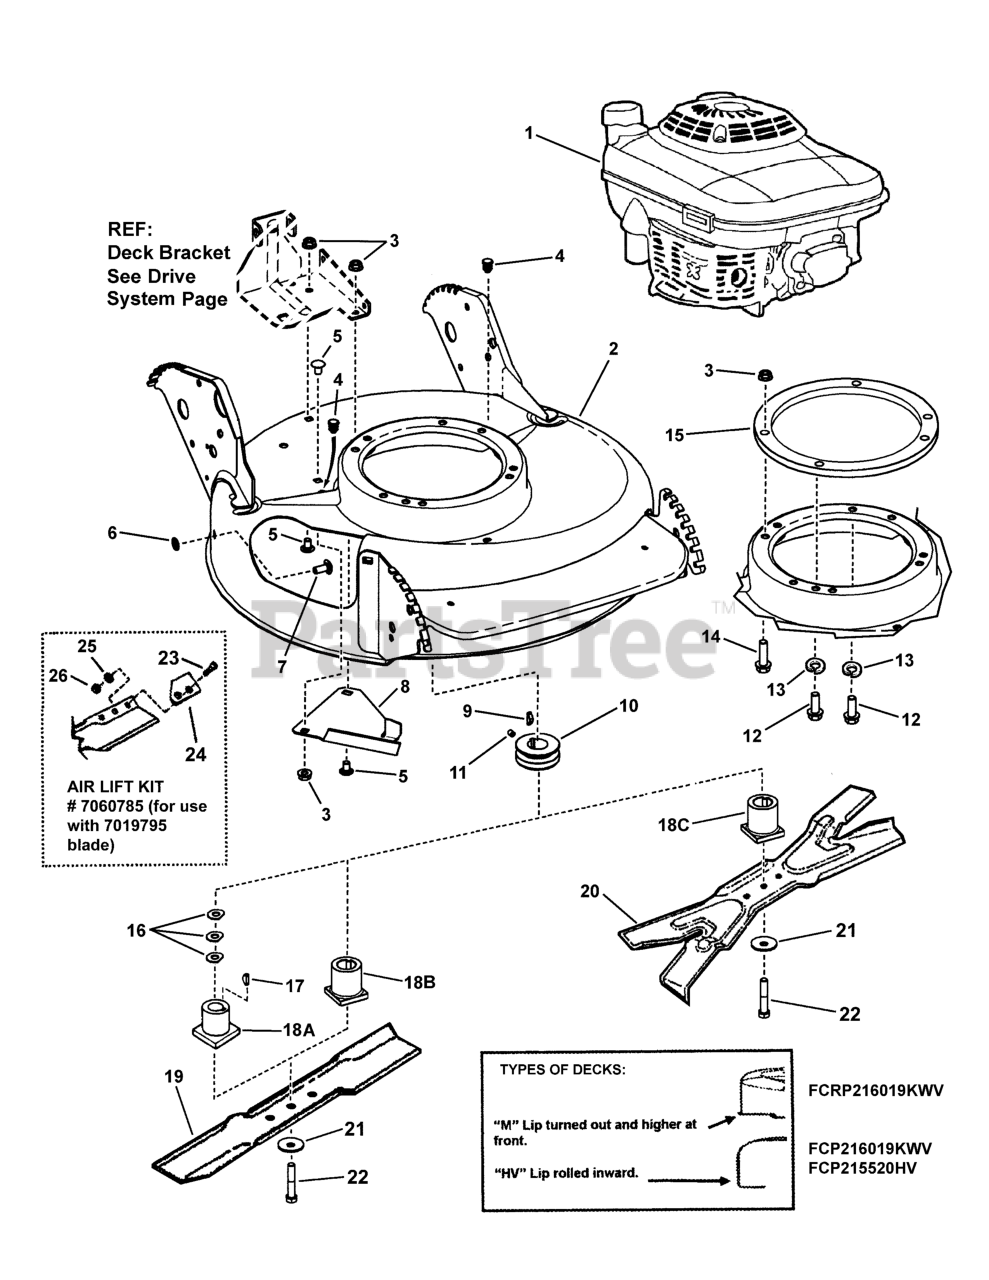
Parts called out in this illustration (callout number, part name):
1	* ENGINE, 6 HP Kawasaki w/side recoil, Mod. FJ180V-DS13-R
1	* ENGINE, 6 HP Kawasaki w/side recoil, Mod. FJ180V-BS23-R
2	** WELDMENT, Deck, 21" Non-Adjust Air
2	** WELDMENT, Deck, 21", S.P., Hi-Vac
3	NUT, 5/16-18 Hex Flange Lock GR 5
4	PLUG, Hole, Polyethylene
5	BOLT, 5/16-18 x 1/2", Short Neck Carriage, GR 5
6	RETAINER, 5/16" Bolt
7	BOLT, 5/16-18 x 3/4" Short Neck Carriage GR 5
8	COVER, Belt
9	KEY, Woodruff #HP-506 Hi-Pro
10	PULLEY- Engine (25mm I.D. x 2-1/8" O.D.)
10	PULLEY- Engine (1.085 I.D. x 2-1/8" O.D.)
11	SCREW, 5/16-18 x 5/16" Hex Socket Head
11	SCREW, 5/16-18 x 1/2" Hex Socket Head
12	SCREW, 5/16-24 x 1-1/4" Hex Head Cap GR 5
13	WASHER, .32 x .58 x .08 Split Lock
14	BOLT, 5/16-18 x 1-1/2" Hex Flange Lock, GR5
15	RING, Engine Spacer
16	SPACER, .06 Blade Hub
17	KEY, #505 Hi-Pro
18A	*** HUB, Blade Drive, 7/8" I.D.
18B	*** HUB, Blade Drive, 25mm I.D.
18C	*** HUB, Blade Drive, 25mm I.D. RD 2 Position
19	BLADE, Cutter (Standard Lift)
20	BLADE, 21" Ninja (Quad Edge)
21	WASHER, Cone
22	SCREW, 3/8-24 x 2" Hex Head Cap, GR 5
23	SCREW, 5/16-24 x 21/32" Oval Head Machine
24	AIR LIFT
25	WASHER, 5/16" Internal Tooth Lock
26	NUT, 5/16-24 Hex, GR 5
